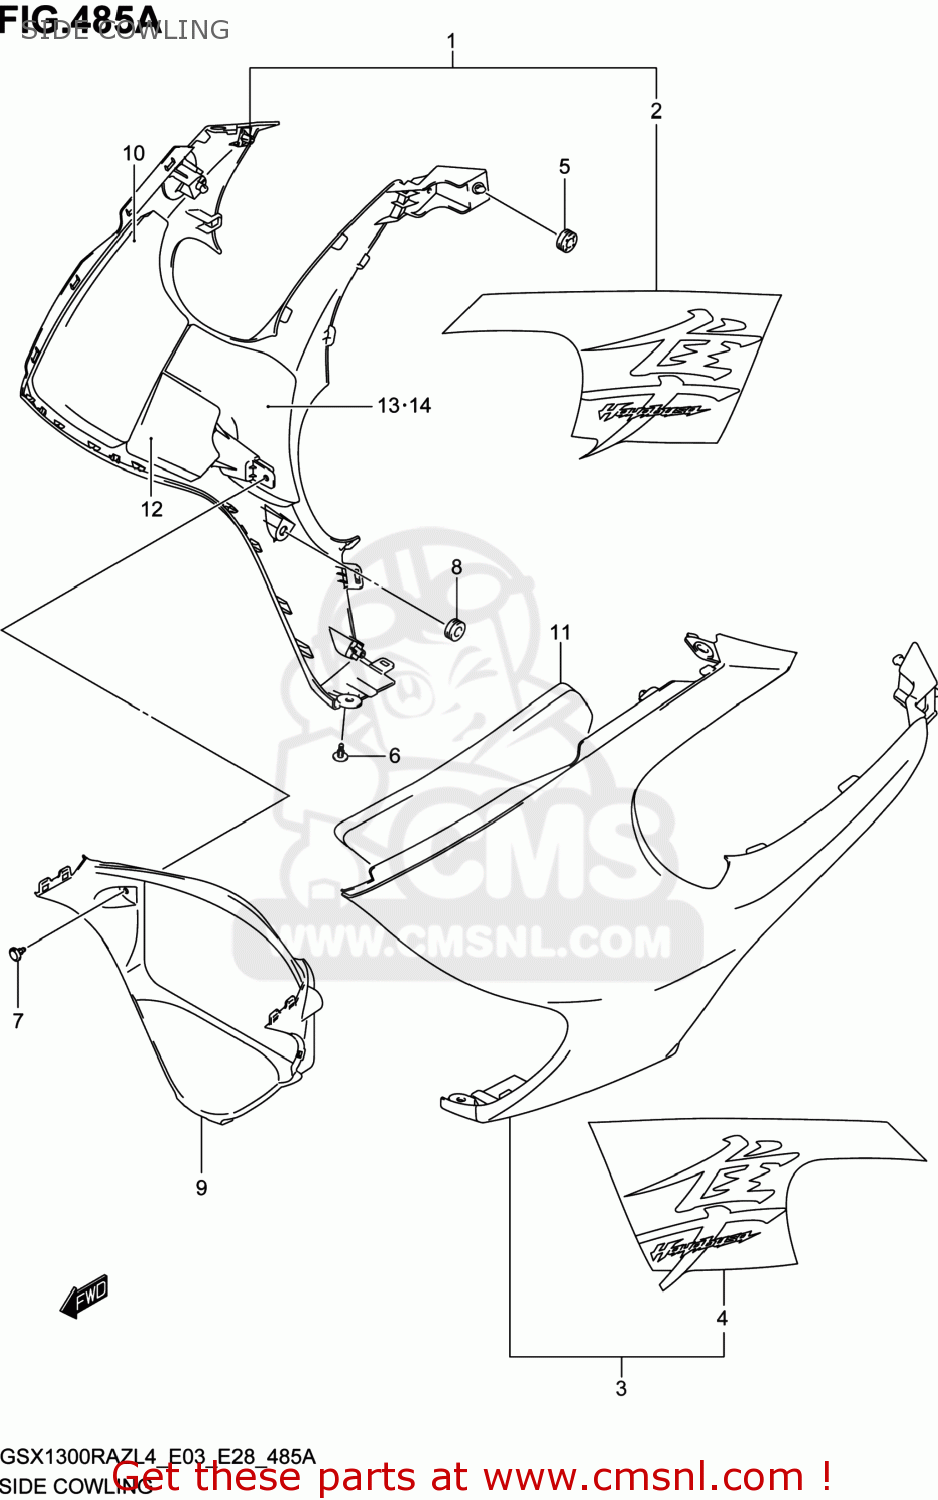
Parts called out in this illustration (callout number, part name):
1	COWLING,SIDE,R(BLACK)
2	TAPE,SIDE COWLING,R
3	COWLING,SIDE,L(BLACK)
4	TAPE,SIDE COWLING,L
5	CUSHION
6	CLIP
7	CLIP
8	CUSHION
9	COWLING,UNDER CTR
10	CUSHION,SIDE COWL,R
11	CUSHION,SIDE COWL,L
12	CUSHION,SIDE COWL
13	SHIELD,SIDE COWL,R
14	SHIELD,SIDE COWL,L
